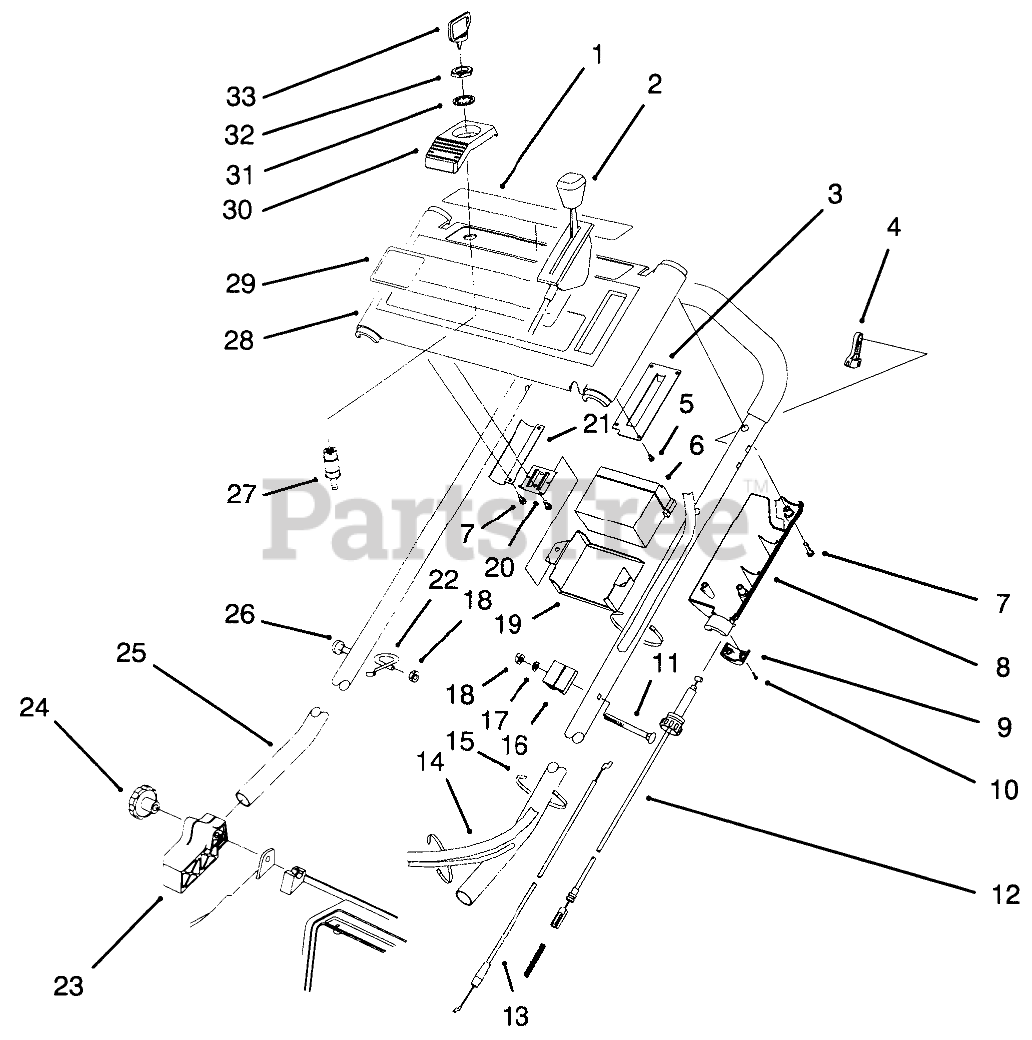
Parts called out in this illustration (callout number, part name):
1	Decal-Instruction
2	CONTROL - THROTTLE
3	THROTTLE PLATE
4	LEVER-TRACTION
5	#6-19X.25 PLASK FORM SC
6	BATTERY ASSEMBLY
7	SCREW-PPH, PLASTITE
8	COVER-THROTTLE, LEVER
9	LOWER THROTTLE CAP
10	#4-14X.62 PLASTITE SCW
11	SCREW-HANDLE
12	CABLE - TRACTION
13	CABLE - BRAKE
14	Harness-Wire
15	TIE-CABLE
16	SUPPORT-CABLE
17	WASHER-FLAT
18	NUT-LOCK, NI
19	Retainer-Battery
20	BATTERY BRACKET
21	Bracket-Panel
22	GUIDE-ROPE
23	MOUNT-HANDLE, RH
25	HANDLE (DIPPED)
26	Screw-Handle
27	Switch-Starter (Incl. Ref. #31 & 32)
28	Panel-Control (Incl. Ref. #1 & 29)
29	DECAL - PANEL KEY
30	IGNITION SWITCH BRACKET
31	WASHER-TOOTH, INTERNAL
32	NUT-HH
33	KEY-IGNITION
